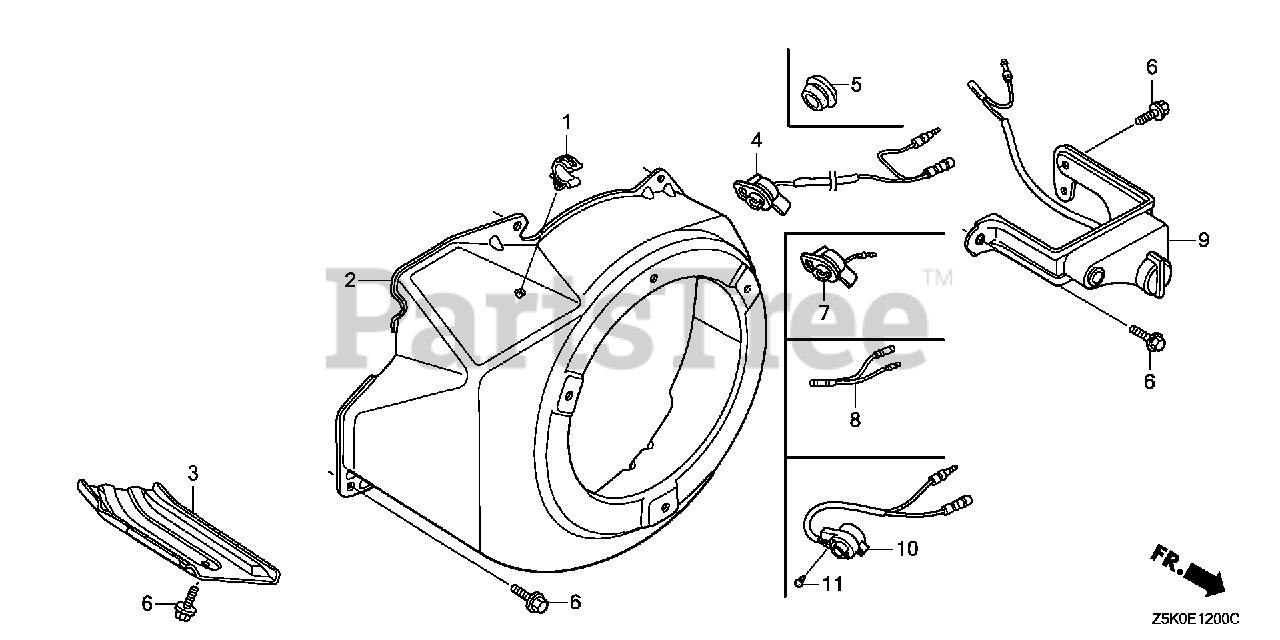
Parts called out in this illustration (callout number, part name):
1	CLIP, TUBE
2	COVER, FAN *R280* (POWER RED)
4	SWITCH ASSY., ENGINE STOP
6	BOLT, FLANGE (6X12) (CT200)
